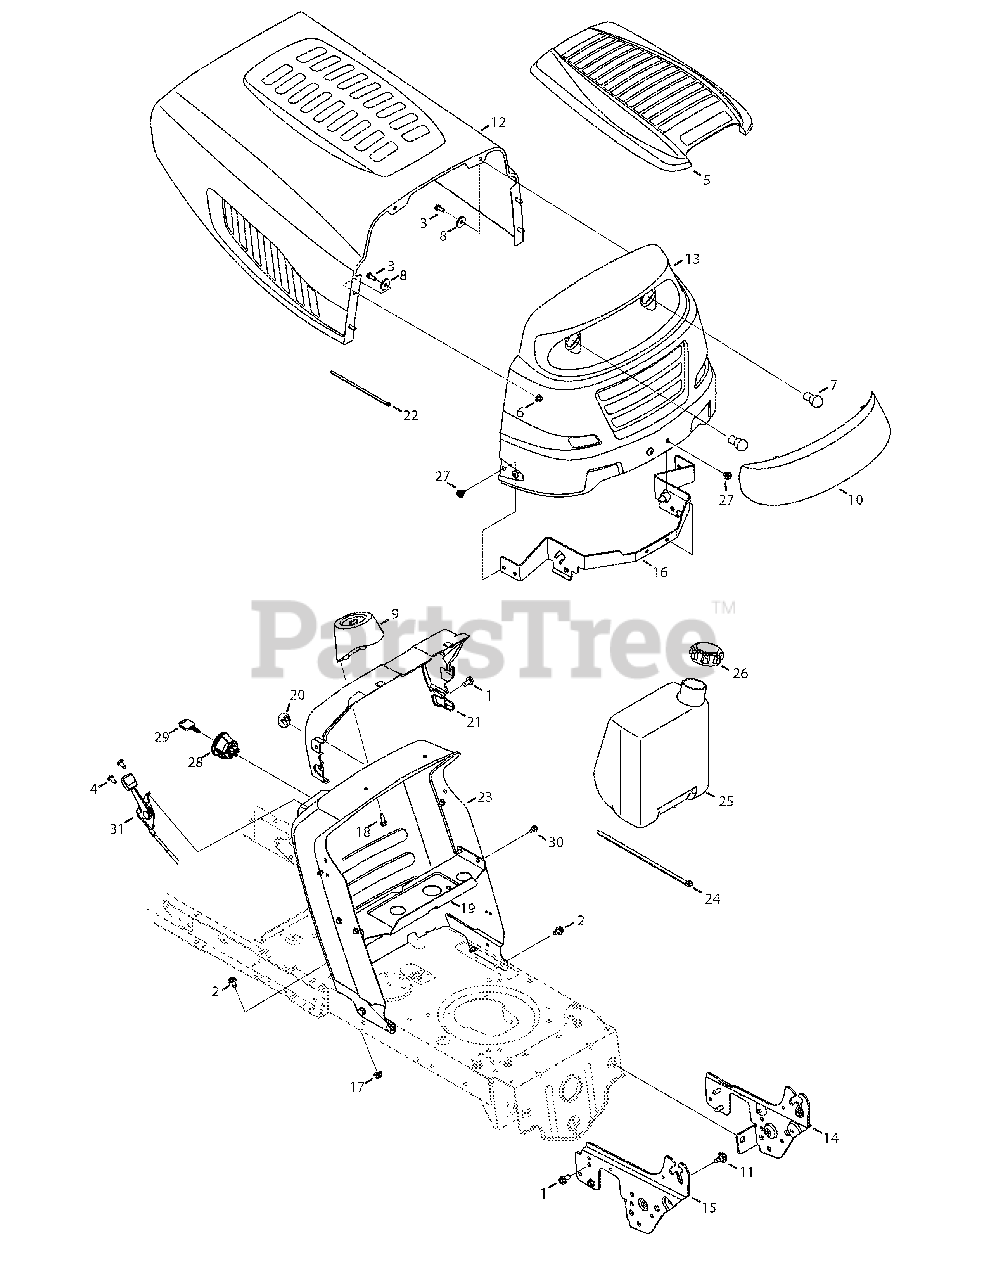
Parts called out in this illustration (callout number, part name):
1	Self-Tapping Screw 5/16-18 x .750
2	Screw, 5/16-18, 0.625
3	Screw, 1/4-20, .620, Gr5
4	Screw, 1/4-20, .500
5	5-Style Hood Cover
6	Nut, Flange Lock, 1/4-20, Gr5
7	Headlamp, 12V
8	Washer, Flat, .265 x .938 x .120
9	Support, Steering
11	Screw, Shoulder, .43 x.29, 5/16-18
17	Flange Lock Nut 5/16-18
18	Screw, 1/4-15, 0.750
20	Dash Plug
21	Collar, Dash
22	Cable Tie
24	Cable Tie, 34.75
25	Fuel Tank, 1.5 gal.
26	Fuel Tank Cap
27	Self-Tapping Screw 5/16-18 x .375
28	Igntion, Switch (No RMC) 3 Pos.
28	Igntion, Switch (No RMC) 4 Pos.
29	Key
30	Screw, 1/4-20, 0.500
31	Throttle/Choke Control, 25"
